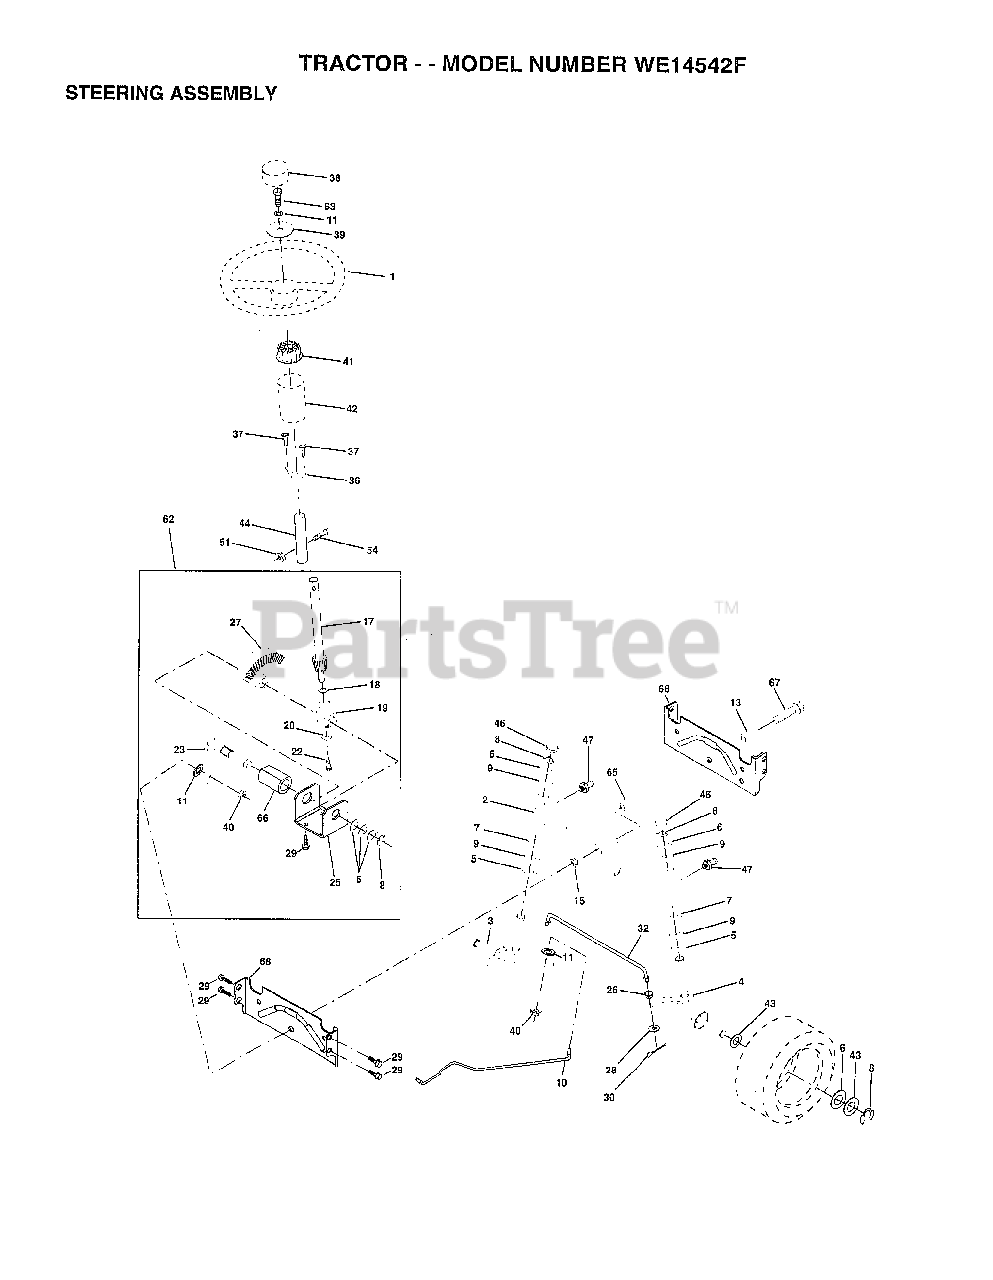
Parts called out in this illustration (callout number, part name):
1	WHEEL STR AYP BLK
2	AXLE ASM
3	SPINDLE.ASM.LH
4	"SPINDLE ASM,RH"
5	WASHER .T
6	WASHER
7	WASHER
8	RING
9	COL. SRTG. BEAR.
10	DRAGLINK-STAMPED
11	LOCKWASHER
13	BEARING AXLE
15	"NUT-LOC,FLANGE LT"
17	SHAFT ASM STEERIN
18	THRUST WASHER
19	SUPPORT.SHAFT
22	SCREW HEX SOC1/4-
25	BRKT-STEERING
26	BUSHING.DRAGLINK
27	GEAR SECTOR
28	WASHER
29	SCREW
30	COTTER PIN
32	TIE ROD
36	BUSHING.STEERING
37	"SCREW-TT,10-32 FL"
38	CAP STEER AYP
39	WASHER T
40	GRIPCO NUT
41	ADAPTER LT
42	BOOT.STEER.PL
43	WASHER
44	EXT SHAFT STEERIN
46	CAP
47	ZERK M
51	NUT
54	BOLT
62	KIT STEERING ASM
63	BOLT
65	SPACER AXLE
66	"BEARING-ARM,PITMA"
67	BOLT
68	BRACE AXLE
